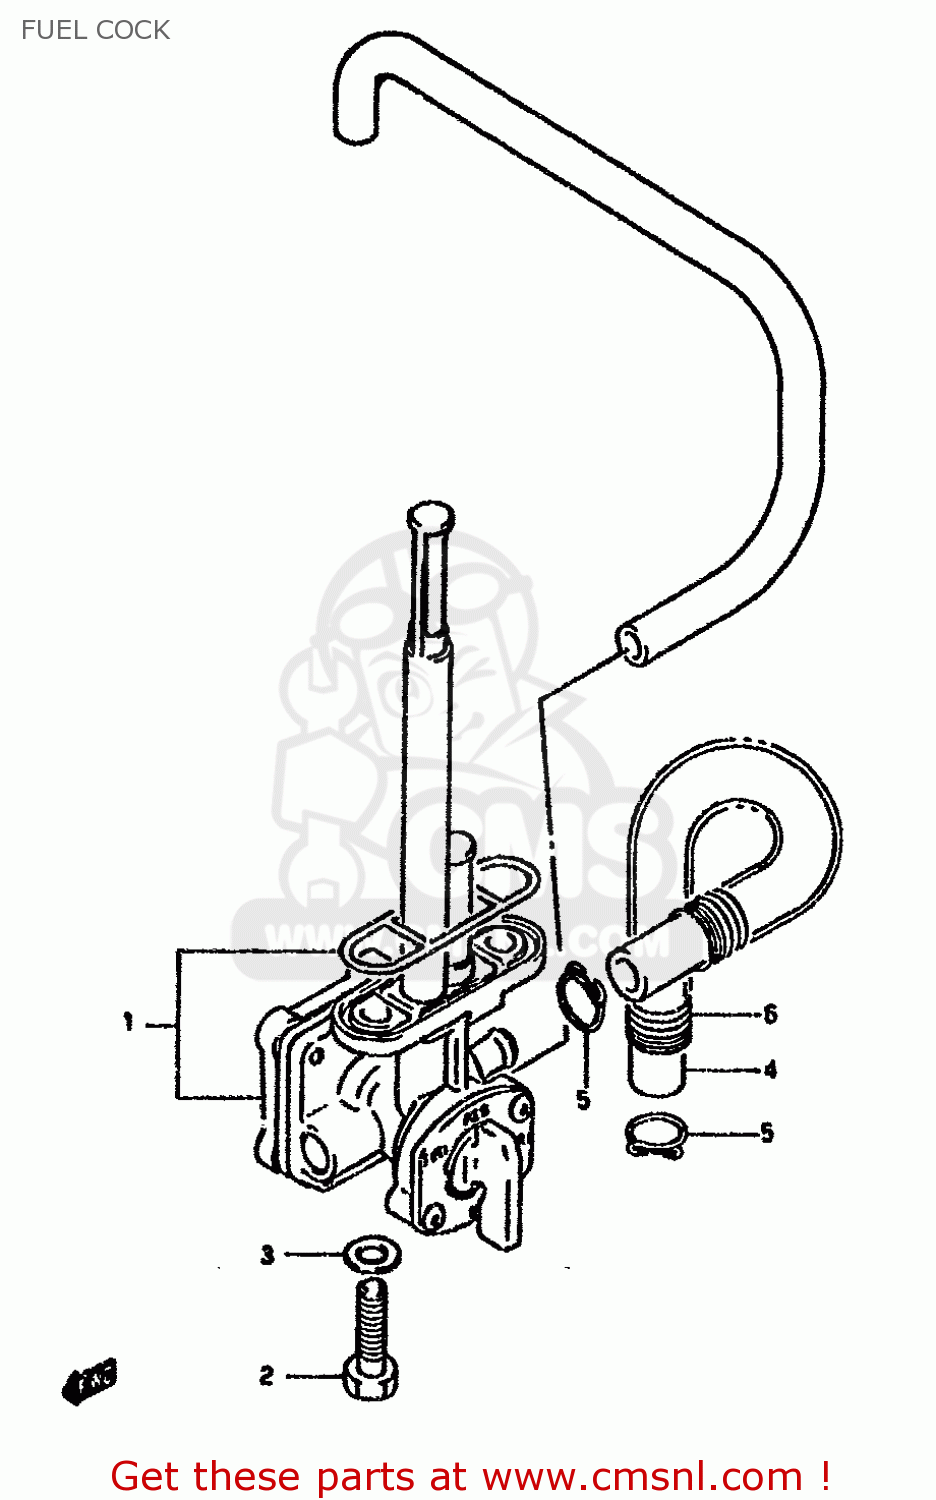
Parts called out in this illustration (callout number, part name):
1	COCK ASSY,FUEL
2	BOLT(6X20)
3	GASKET(6.4X11.5X0.8) (NAS)
4	HOSE
5	CLIP
6	SPRING
